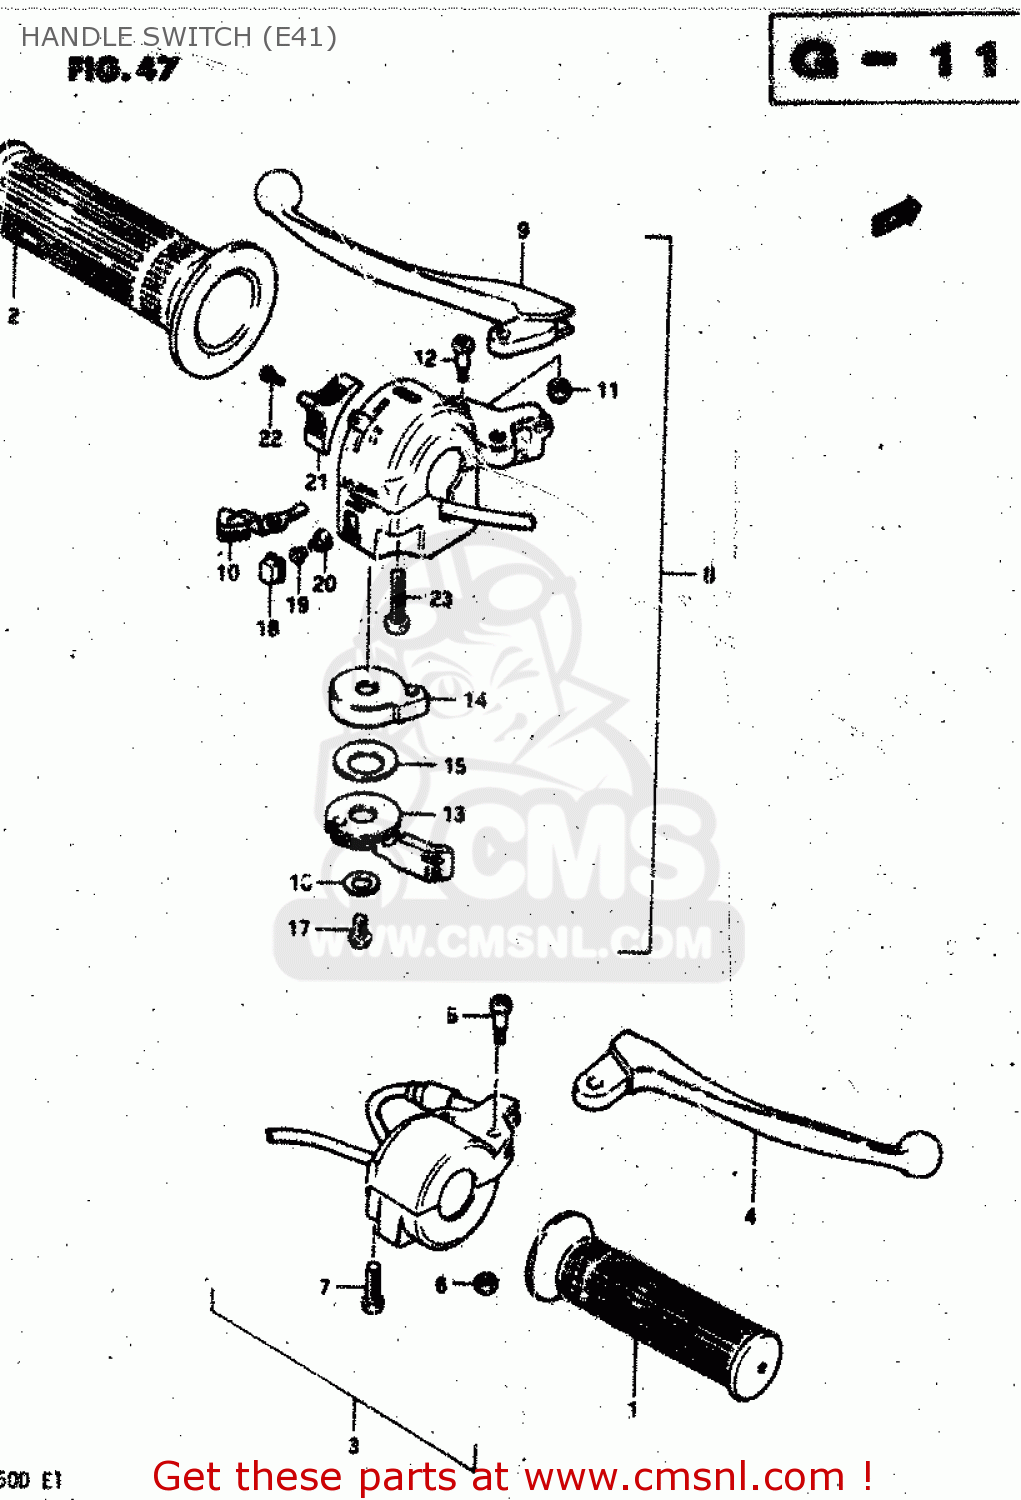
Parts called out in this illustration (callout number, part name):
1	GRIP,THROTTLE
2	GRIP,L
3	BRAKE LEVER & SWITCH ASSY
4	LEVER
5	BOLT,LEVER
6	NUT,LEVER BOLT
7	SCREW
8	CLUTCH LEVER & SWITCH ASSY
9	LEVER
10	KNOB,TURN SIGNAL SWITCH
11	NUT,LEVER BOLT
12	BOLT,LEVER
13	LEVER,STARTER
14	BODY,STARTER LEVER
15	WASHER,ADJUSTER
16	WASHER
17	SCREW
18	BUTTON,HORN
19	CONTACT
20	SPRING
21	KNOB
22	SCREW 3X6
23	SCREW
